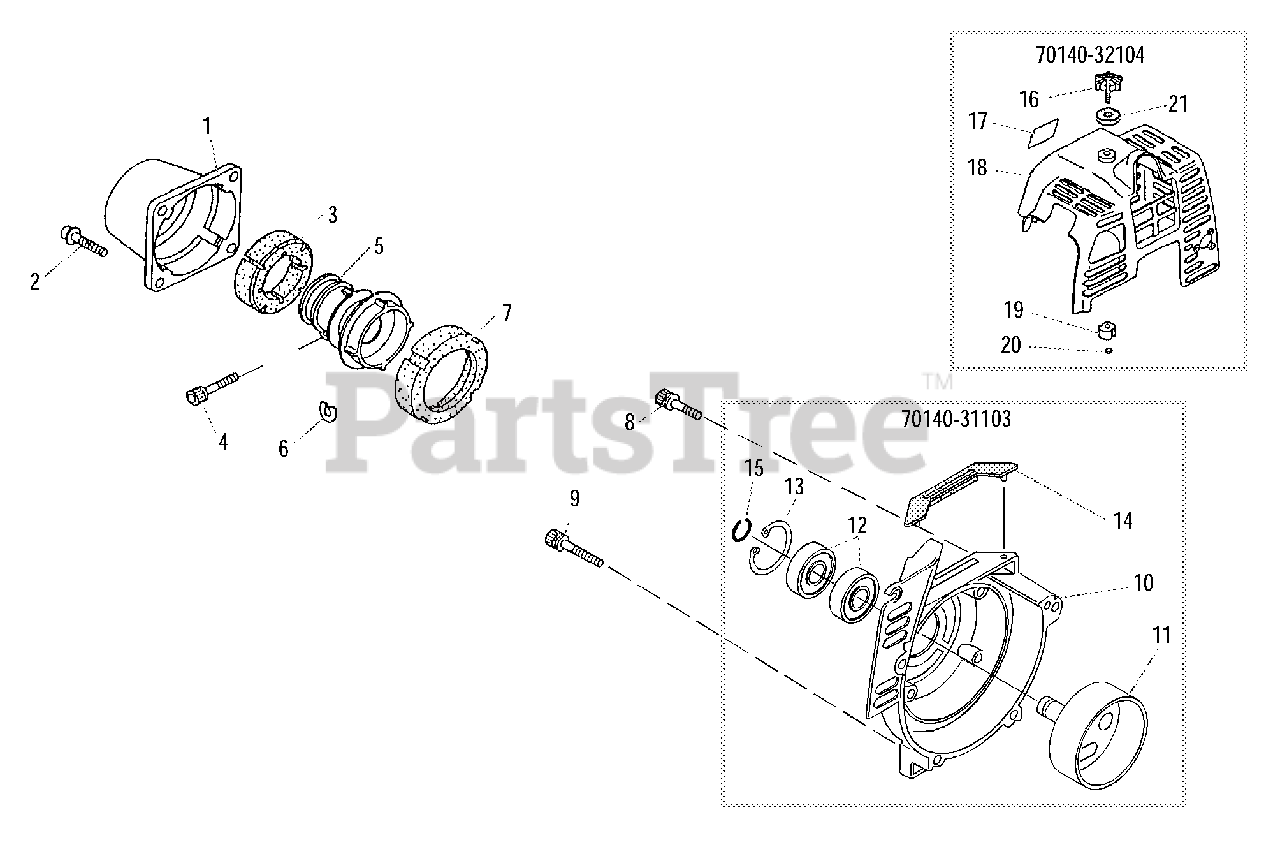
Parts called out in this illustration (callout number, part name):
1	CAP
2	SCREW - 5X16
3	CUSHION - FRONT
4	SCREW - 5X25
5	CLAMP, MAIN PIPE
6	SHIM
7	CUSHION - REAR
8	SCREW - 5X16
9	SCREW - 5X35
10	CASE, FAN
11	DRUM, CLUTCH
12	BEARING, BALL - 6000
13	RING, RETAINING - 26
14	CUSHION
15	RING, RETAINING
16	THUMBSCREW
17	LABEL
18	COVER, ENGINE
19	INSULATOR
20	CLIP
21	WASHER - CONICAL
70140-31103	FAN CASE ASSY
70140-32104	ENGINE COVER KIT - RED
